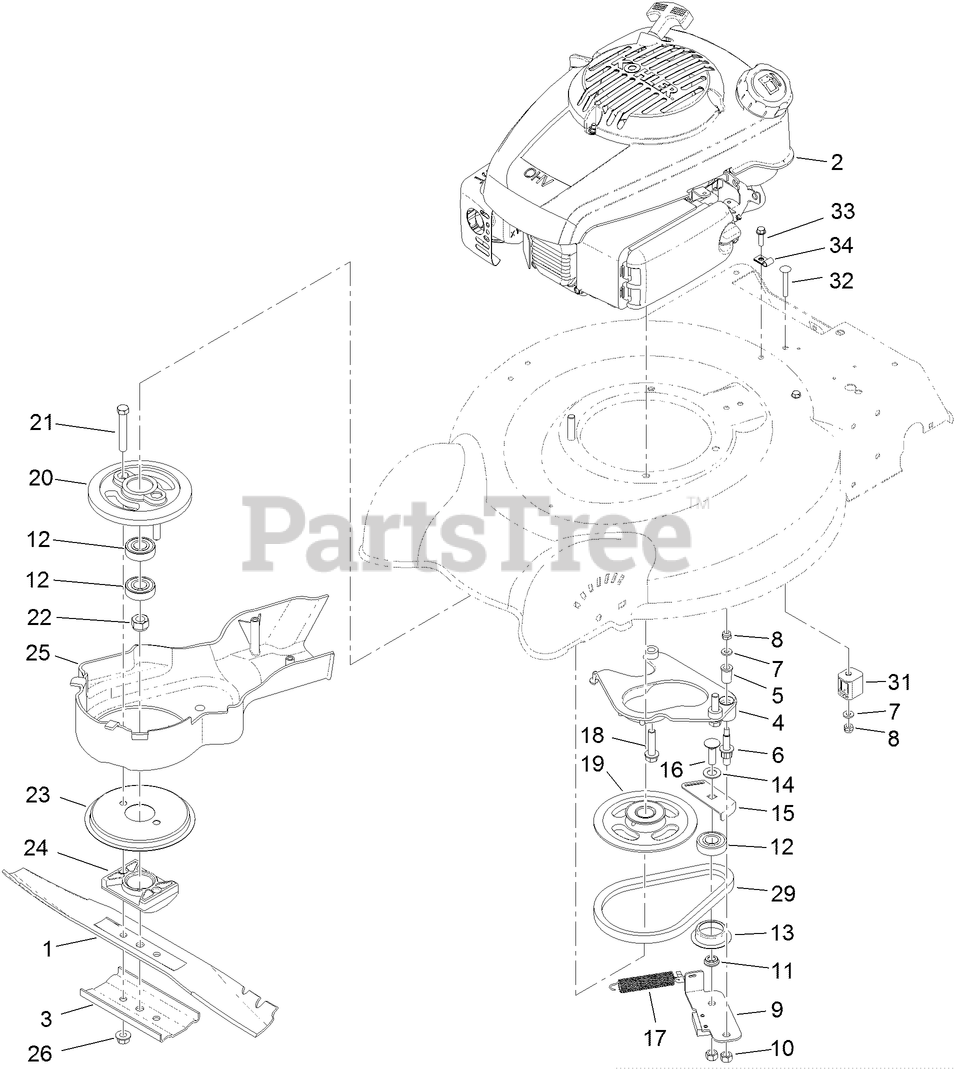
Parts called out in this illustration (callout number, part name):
3	SUPPORT-BLADE
4	PLATE-ANCHOR
6	BOLT-SHOULDER
7	WASHER-FLAT
8	NUT-LOCK, NI
10	LOCKNUT
11	SPACER-BEARING
13	RETAINER-BELT
15	PLATE-GUIDE
16	BOLT-CARR
17	SPRING-TENSION, BRAKE
18	SCREW-HWH
21	SCREW-HH
23	DISC
24	SUPPORT-BLADE
25	COVER-BBC
26	NUT-LOCK
31	ANCHOR-CABLE
32	SCREW-CARR
33	SCREW-HWH
34	CLIP-CLOSED, INSULATED
